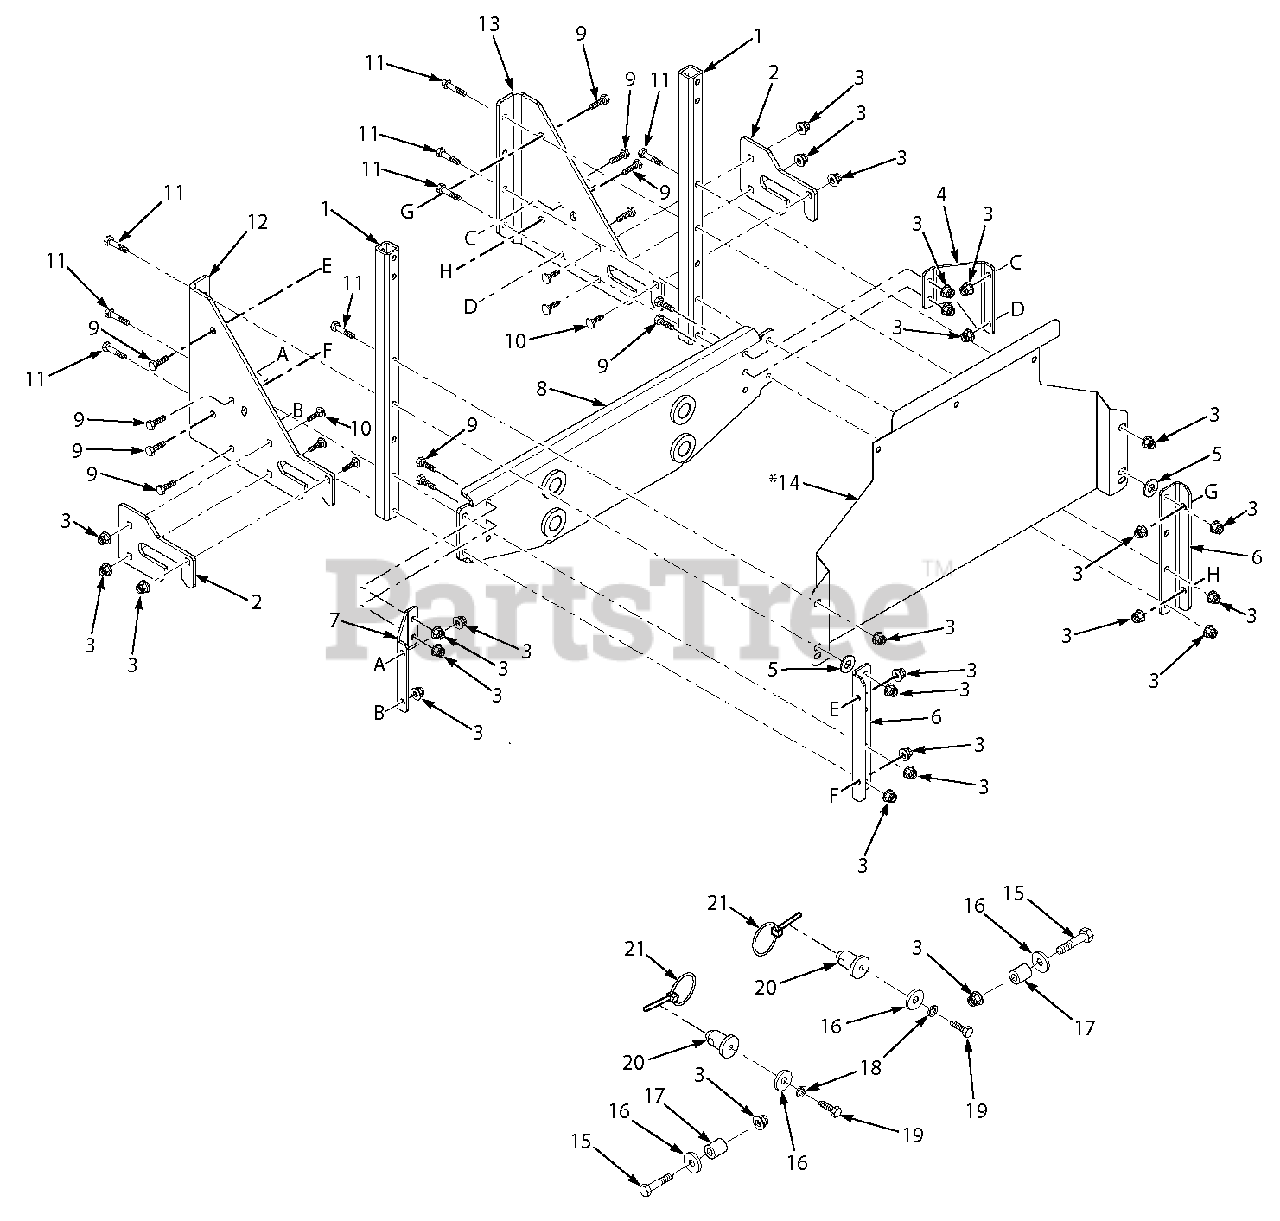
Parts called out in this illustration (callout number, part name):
1	Tube, Upright
2	Wear Plate, GC
3	Nut, Elastic Flange 3/8-16
4	Angle Brace, LH GC
5	Flatwasher, .469 X 1.75 X .25
6	Mounting Bracket, GC Tube
7	Angle Brace, RH GC
8	Mounting Bracket Weldment
9	Bolt, Hex Head 3/8-16 x 1"
10	Bolt, Carriage 3/8-16 x 1"
11	Bolt, Hex Head 3/8-16 x 2-1/2"
12	RH Mounting Bracket, GC
13	LH Mounting Bracket, GC
14	Heatshield (used on STT & STTII Models Only)
15	Bolt, Hex Head 3/8-16 x 2-1/4"
16	Flatwasher, 3/8-.406 x 1.50 x 7 Ga.
17	Spacer
18	Lockwasher, 3/8"
19	Bolt, Hex Head 3/8-16 x 1-1/4"
20	Pin, GC Locator
21	Quick Pin
